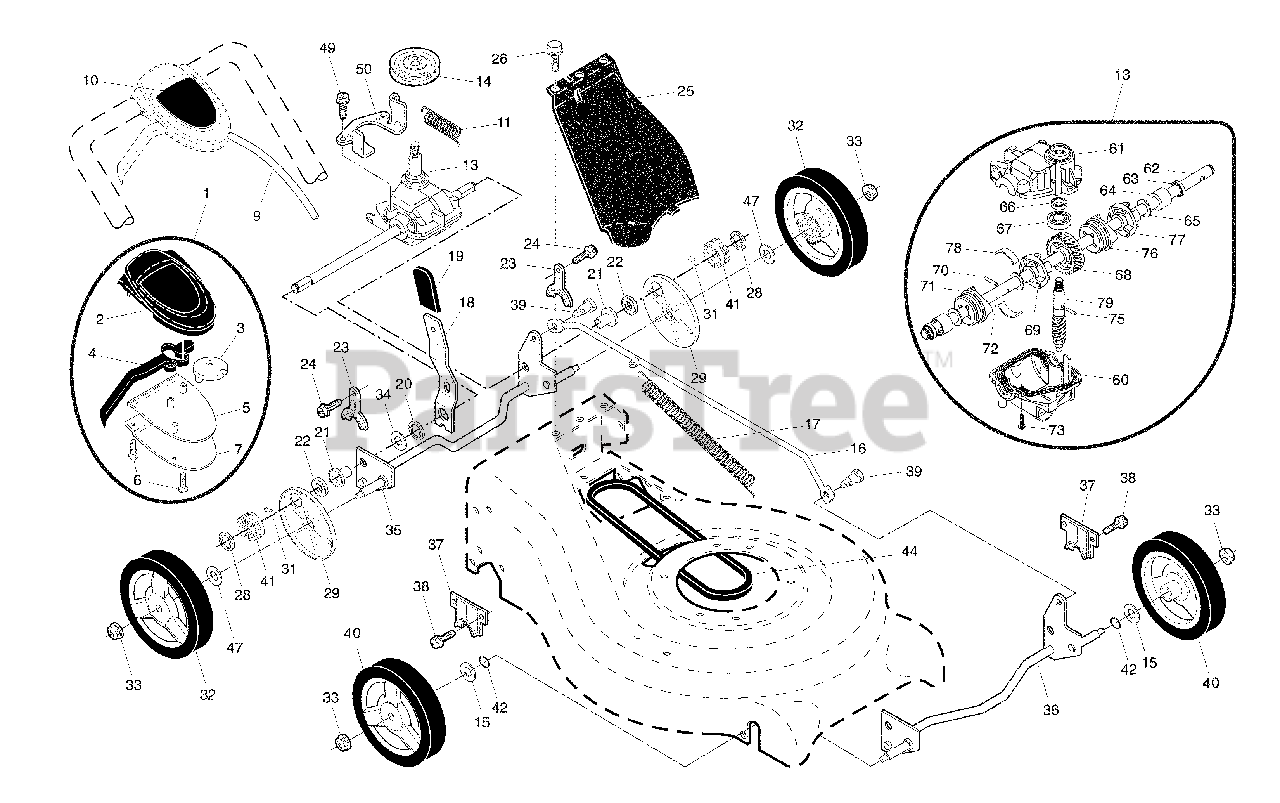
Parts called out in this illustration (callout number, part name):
1	Drive Control Assembly, Auto-Walk
2	Cover, Top, Auto-Walk Drive Control
4	Lever, Auto-Walk Drive Control
5	Cover, Bottom, Auto-Walk Drive Control
6	Screw, Phillips Head #10 x 5/8
7	Bracket, Drive Control
9	Cable, Drive Control
10	Decal, Drive Control
13	Gear Case Assembly, Complete
14	Pulley, Drive
16	Rod, Connecting
17	Spring, Extension
18	Spring Selector
19	Knob, Selector Spring
21	Bearing, Support
22	Bearing, Ball
23	Retainer, Drive Assembly, Stamped
24	Screw, Tapping, Hex Head 1/4-20 x .75
25	Cover Drive
26	Screw, Threaded, Rolled #10-25 x .50
28	E-Ring 7/16
29	Cover, Dust, Wheel
32	Wheel, Driven, Rear 8 x 1-3/4
33	Nut, Hex, Flangelock 3/8-16
34	Washer, Flat
35	Shaft Assembly, Rear
36	Shaft Assembly, Front
37	Retainer, Front Shaft
38	Screw #12 x 5/8
39	Bolt, Shoulder, Semi-Gimlett Point
40	Wheel, Front 8 x 1-3/4
47	Washer 1/2 x 1-1/2 x .134
49	Screw #12 x 5/8
50	Bracket, Belt
60	Case, Lower
61	Case, Upper
62	Shaft, Output, Long
63	Seal, Output Shaft
66	Seal, Worm Shaft
67	Bearing, Ball
68	Gear, 28 Teeth
69	Fixed Dog Clutch, LH
70	Pin, Output Shaft
71	Movable Dog Clutch, LH
72	Shaft, Output, Short
73	Screw, Case
75	Pin, Worm Shaft
76	Fixed Dog Clutch, RH
77	Movable Dog Clutch, RH
78	Spring, Leaf
79	Shaft, Worm
